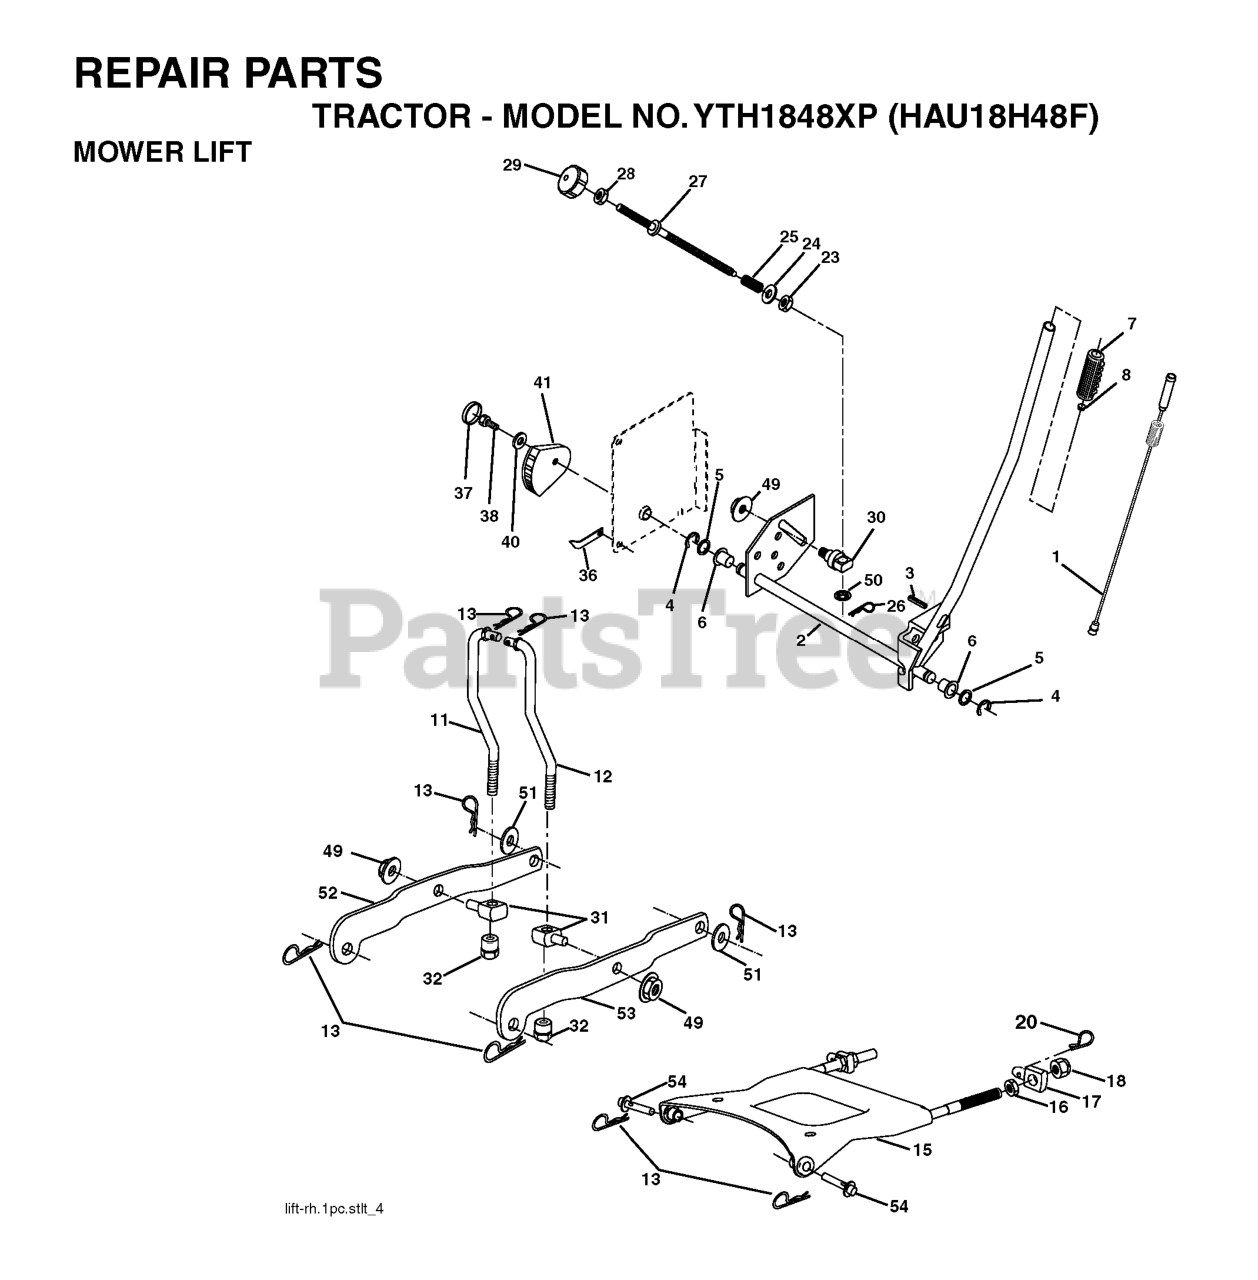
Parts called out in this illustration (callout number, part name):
1	WIRE ASM INNER W/ PLUNGER LT
2	SHAFT ASM R HANDLE
3	PIN GROOVE.
4	RETAINING RING LT
6	BEARING.NYLON
7	GRIP HANDLE
8	PLUNGER BUT KIT
11	LIFT LINK LH
12	LIFT LINK RH
13	RETAINER-SPRNG RB
15	PLATE ASM SUSP FRONT
16	NUT.HEX.JAM.1/2-13
18	NUT.LK.W/WSH.1/2.
20	SPRING RETAINER
25	SPRING**
26	RETAINER CLIP
27	ROD ADJ LIFT
28	NUT
29	KNOB INF 3/8-16
32	NUT, LIFT LINK 7/16-20
36	POINTER, HEIGHT INDICATOR(2 2)
38	SCREW 5/16-18X1
41	IND. HEIGHT STLT
49	NUT
50	NUT PUSH M
51	Washer 1 17/32 X 7/8 X 16 Ga
52	ARM SUSP. REAR LH
53	ARM SUSP REAR RH
54	PIN.FLANGE
